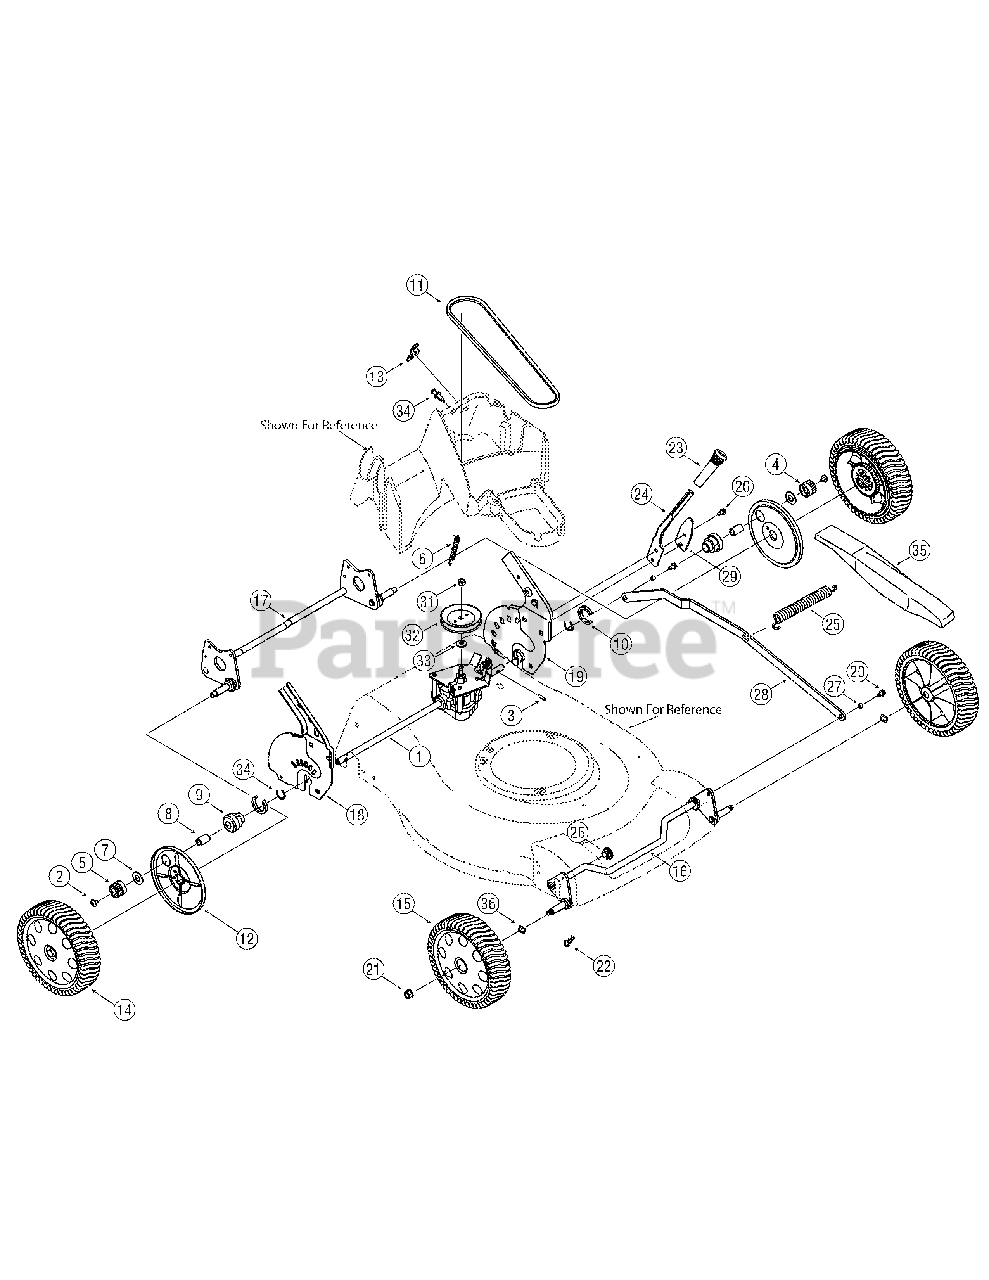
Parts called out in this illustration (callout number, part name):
1	Transmission Assembly
2	Screw, M6 x 1.0
3	Dowel Pin
4	Spur Gear, 14T - LH
5	Spur Gear, 14T - RH
6	Extension Spring, .38 OD x 3.24
7	Flat Washer, .51 x 1.120 x .062
8	Sleeve Bearing, .502 x .627 x 1.00
9	Transmission Bearing Support
10	Clip Spacer
11	V-Belt
12	Wheel Dust Cover
13	Transmission Cable Bracket
14	Rear Wheel
15	Front Wheel
21	Flange Lock Nut, 3/8-16
22	Cotter Pin
24	Spring Lever
25	Extension Spring, .500 ID x 6.85 Lg
26	Split Hex Flange Bearing
27	Spacer
30	Retaining Ring .875
31	Hex Lock Nut, 5/16-24
32	Pulley, 3.36 OD
33	Bell Washer, .375 x .870 x .063
34	Plastic Rivet
34	Retaining Ring .875
35	Spring Bracket Cover
36	Wave Washer, .510 x .750 x.017
